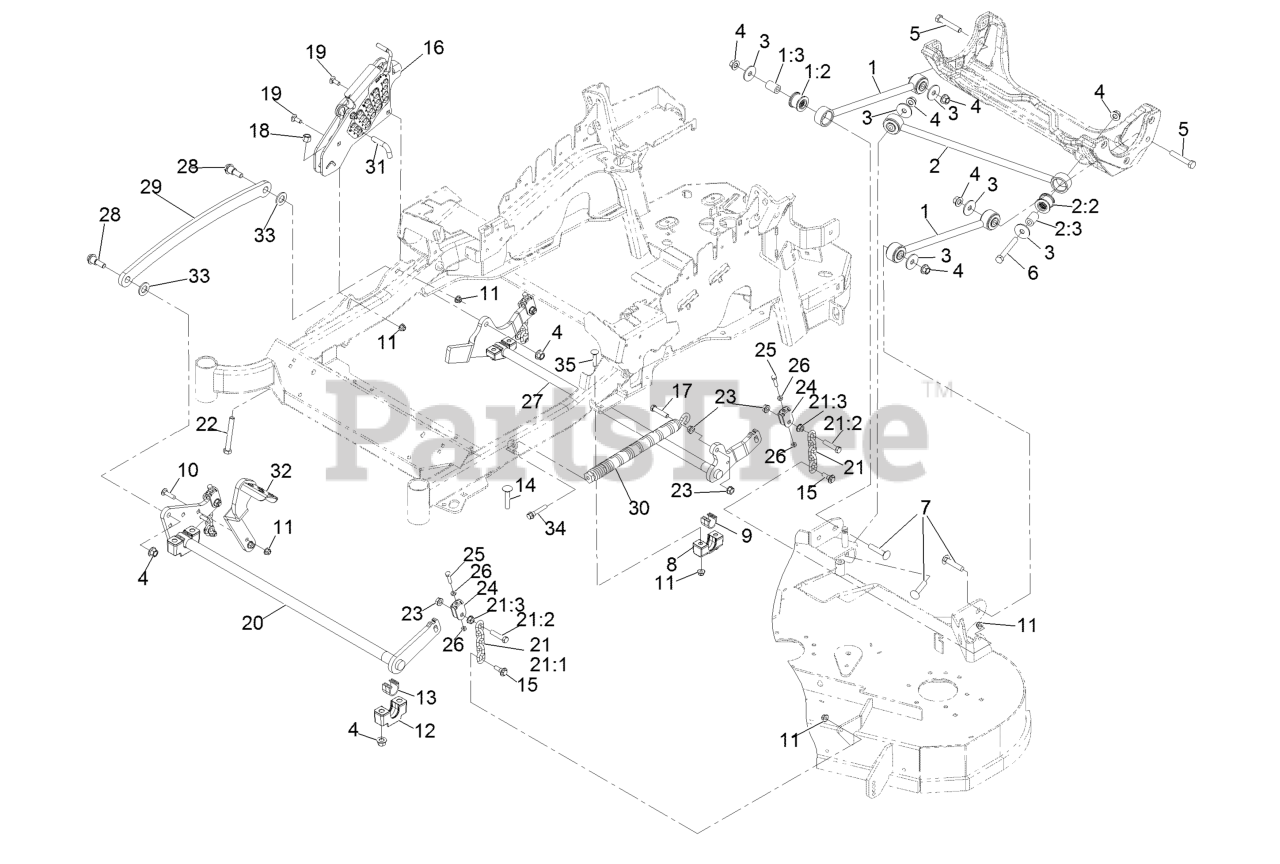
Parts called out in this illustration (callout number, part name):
1	Deck Strut ASM
1:2	Bushing-Suspension, Rubber
2	Panhard Rod ASM
2:2	Bushing-Suspension, Rubber
4	Nut-Lock 1/2-13
5	Screw-HH 1/2-13 X 3
6	Screw-HH 1/2-13 X 4
7	Bolt-Carriage 1/2-13 X 2 1/2
8	Support-Cross Shaft, Bearing Rear
9	Bearing-Cross Shaft, Rear
10	Bolt-Carriage 3/8-16 X 1 1/2
11	Nut-Nyloc 3/8-16 Flg
12	Support-Cross Shaft, Bearing
13	Bearing-Cross Shaft, Front
14	Bolt-Carriage 1/2-13 X 2 1/2 Spl Neck
15	Screw-Hex Flange 3/8-16 X .80
16	HOC ASM
17	Screw-HH 7/16-14 X 2
18	Nut-Nyloc 1/2-13
19	Bolt-Carriage 3/8-16 X 1
20	Decklift-Front
21	Deck Lift Chain ASM
21:1	Chain-Lift, Deck
21:2	Screw-HH 7/16-14 X 2
21:3	Nut-Whizlock 7/16-14
22	Bolt-HH 1/2-13 X 4 Tap
23	Nut-Whizlock 7/16-14
24	Yoke-Adjust, Deck
25	Screw-HH 5/16-18 X 1 1/4
26	Nut-Jam 5/16-18
27	Lift-Deck, Rear
28	Screw-Shoulder HHF 1/2-13 X 1.12
29	Link-Lift, Deck
30	Spring-Extension
31	Pin-HOC
32	Lever-Foot
33	Washer-3/4 SAE
34	Screw-Shcs 3/8-16 X 2.212
35	Bolt-Carriage 3/8-16 X 2 1/4
